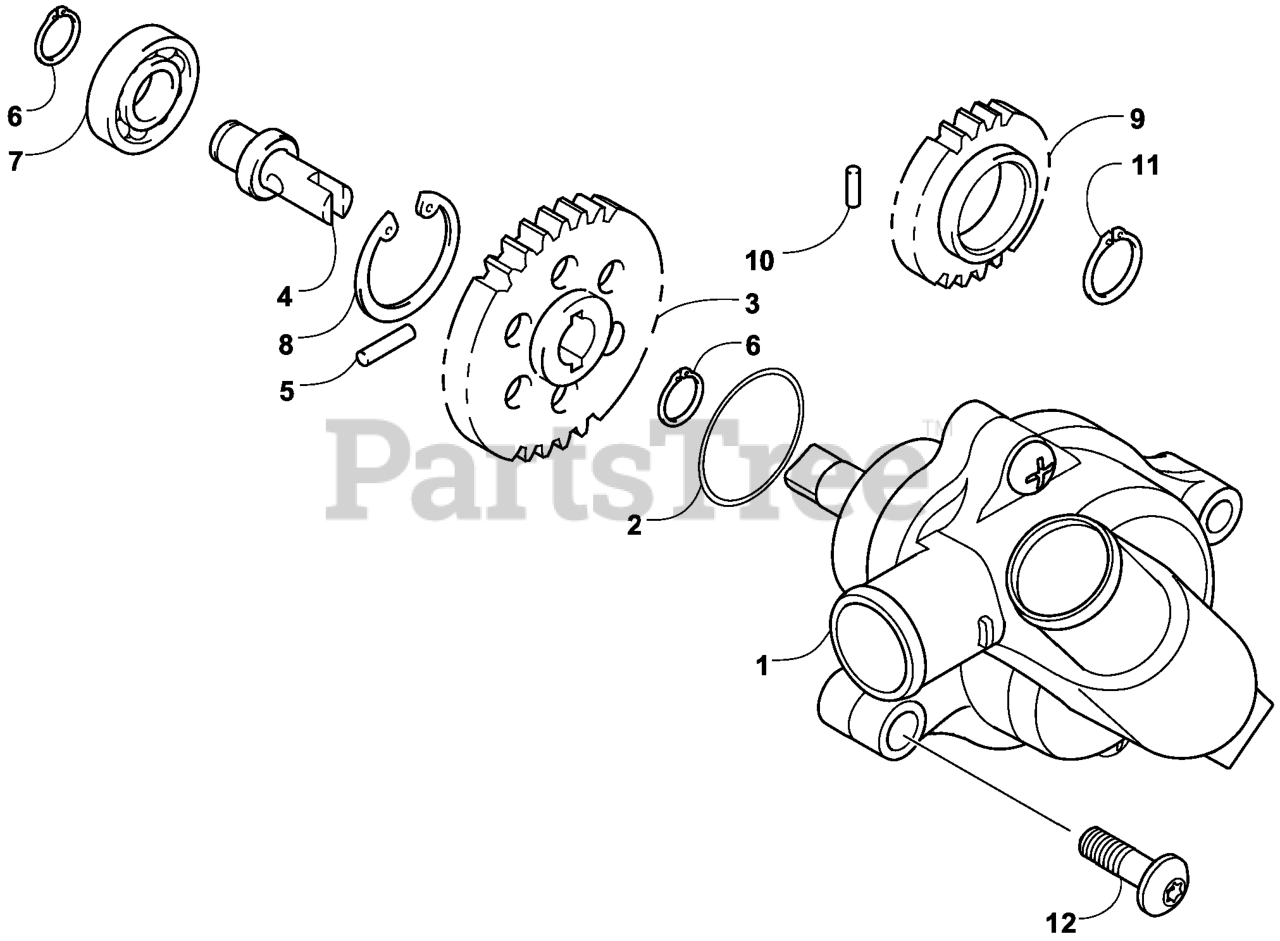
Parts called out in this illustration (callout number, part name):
1	PUMP-WATER
3	GEAR-DRIVEN
4	SHAFT-DRIVEN GEAR
6	RING-RETAINING, EXTERNAL
7	BEARING-SHAFT
8	CIRCLIP-SHAFT BEARING
9	GEAR-DRIVEN, OIL AND WATE
10	DOWEL-SOLID
11	RING-RETAINING, EXTERNAL
12	LEVER,TRANSMISSION
